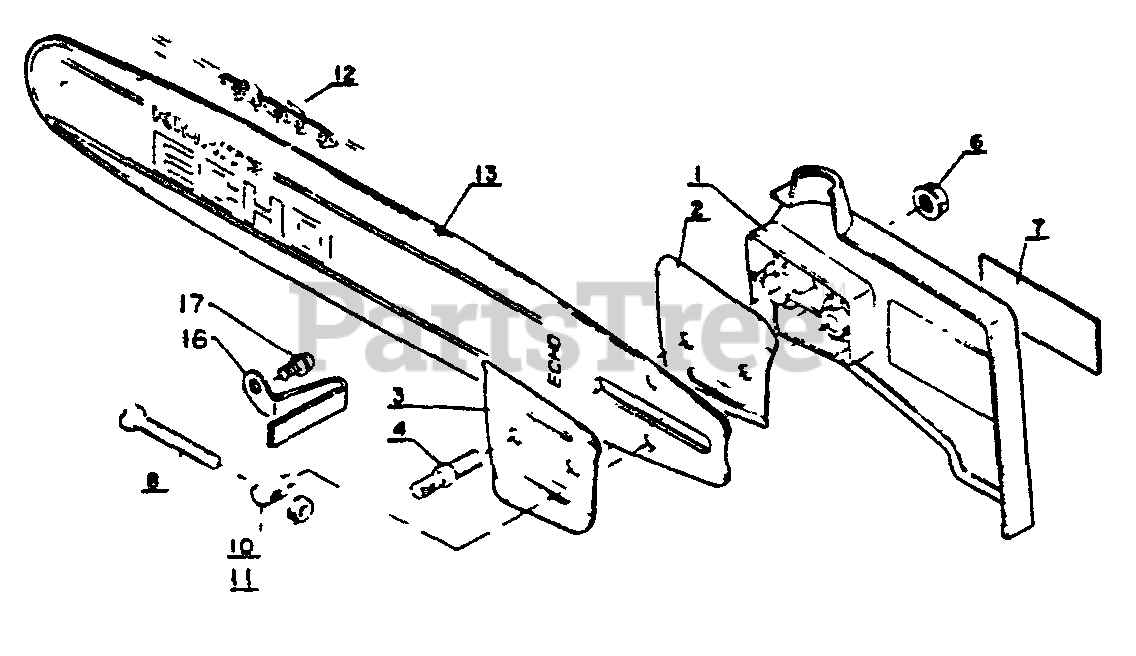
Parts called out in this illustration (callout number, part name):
1	GUARD, SPROCKET
2	PLATE, GUIDE - OUTER
3	PLATE, GUIDE - INNER
4	STUD, GUIDE BAR
6	NUT, FLANGE M6
7	LABEL - ECHO
8	SCREW, ADJUSTER
10	TENSIONER
11	LOCKNUT - 5
16	CHAIN CATCHER
17	SCREW 5×10
